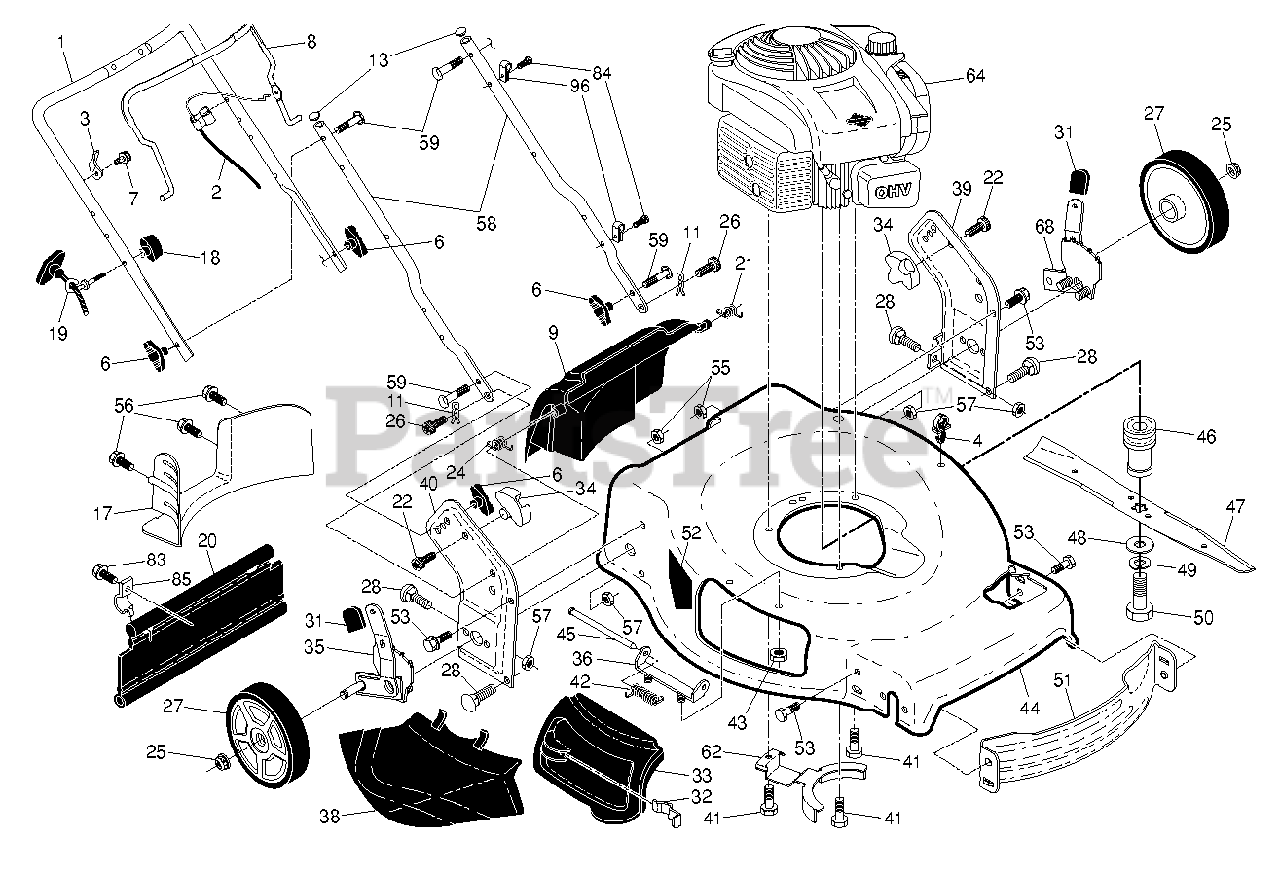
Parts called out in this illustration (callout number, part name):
1	HANDLE.UP.DSTR.EZ.FG/RGD.CREAS
2	CONTROL.ZONE.ASM
3	BRACKET.UPSTOP.RT
4	PUSH CLIP
6	KNOB.HANDLE.PLASTIC.STAR.BLACK
8	BAIL.MZR.EZ2.DSTRT.22+.421
9	DOOR.REAR.22PLUS.MB.FGD.SAFETY
11	COTTER.HAIRPIN.DOOR/HANDLE.PIV
13	PLUG.PLASTIC.7/8".14-20.GAUGE
17	BAFFLE.22PLUS.FGD.REAR.
18	T-KNOB.NEW ROPE GUIDE
19	Rope Guide, Blk Zinc Chrom
20	SKIRT.REAR.22PLUS.RGD/FGD.NEW
21	SPRING.LH.GRAY
22	SCREW.PAN.HEAD.#10
24	SPRING.RH.GRAY
25	NUT.HEX.FLANGE.3/8-16.LOCKNUT
26	SCREW,DOOR/HANDLE.PIVOT
27	WHEEL.8X1.75.CF5SPK.RAD3.BLACK
31	SELECTOR KNOB
32	LATCH.DOOR.ZINC
33	DOOR.MULCH.22.BLACK.MULTI-BRAN
34	BRACKET.GRASSBAG.ATTACHING.BLK
35	ADJUSTER.ASM.9POS.LW.RR/RGD.
36	BRACKET.ASM.HINGE.21.FWGD.
38	DEFLECTOR.CLIPPING.22.BLACK
39	Handle Bracket Assembly, LH 22+ Black
40	Handle Bracket Assembly, RH 22+ Black
41	BOLT 3/8-16X1-1/8
42	SPRING.TORSION
43	NUT.HEX.FLANGE.1/4
45	ROD.HINGE.21
46	ADAPTOR.BLADE.7/8".STAR
47	BLADE.22PLUS
48	WASHER,HARDEN
50	SCREW, HEX HD 3/8-24 X 1-3/8
51	BAFFLE.FRONT.22.PLUS
52	No Step Decal
53	BOLT.5/16HEX.WHS.HD
55	NUT.HEX.FLANGE.1/4
56	SCREW.HX.13X.750
57	NUT.FLANGE.5/16
58	HANDLE.LOWER.22+BT.2PC.BLK
59	BOLT, HANDLE 5/16-18X1.75
62	BRACKET.ENG/BELTKEEPER
68	ADJUSTER.ASM.9POS.HW.R/L
83	TAPPING SCREW
84	FASTENER.PUSH.O.250X0.783
85	BRACKET.SKIRT.22+.BZP
96	CLIP.CABLE.BLK
